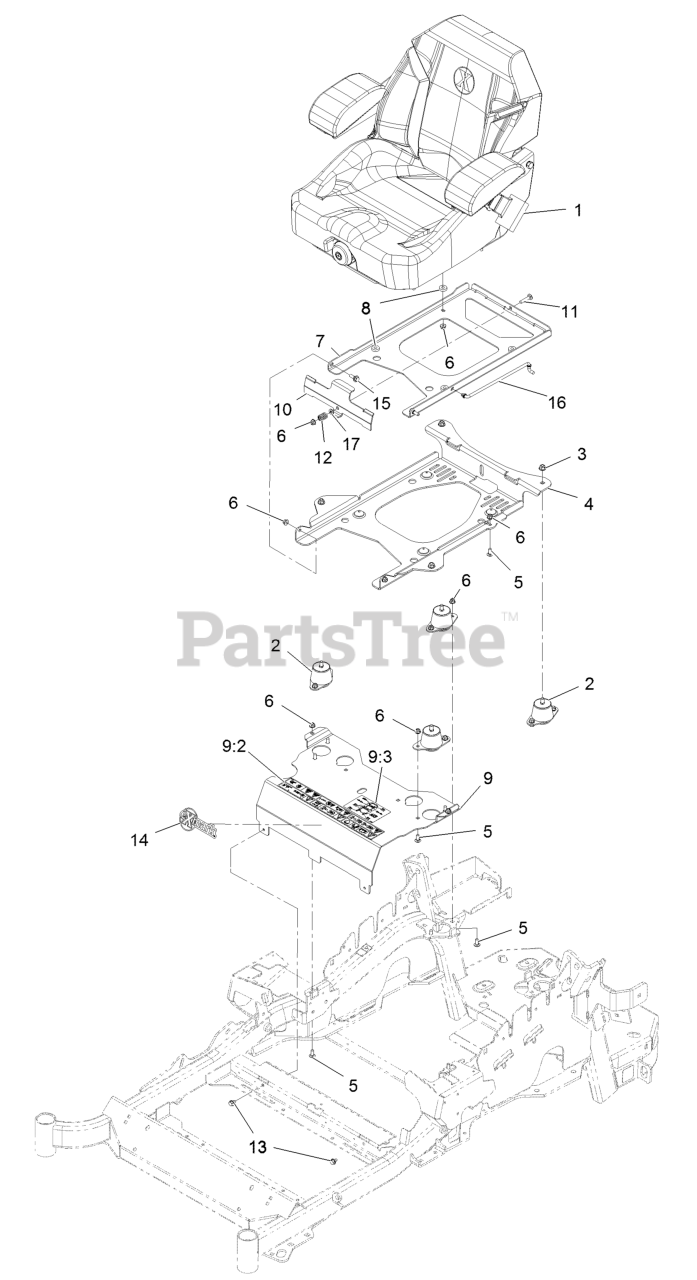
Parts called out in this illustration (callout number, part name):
1	KIT-SUSPENSION SEAT
2	ISOLATOR-SEAT
3	NUT-HF, NI
4	PLATE-TILT, SEAT SUPPORT
5	SCREW-CARR
6	NUT-HF, NI
7	PLATE-FRAME, SEAT
9	MOUNT-SEAT
9:2	DECAL-CONSOLE
9:3	DECAL-SERVICE AID
10	PLATE-LATCH, SEAT
11	BOLT-CARR
12	SPRING-COMPRESSION
15	SCREW-SHOULDER
16	ROD-PROP
17	WASHER-PLAIN
